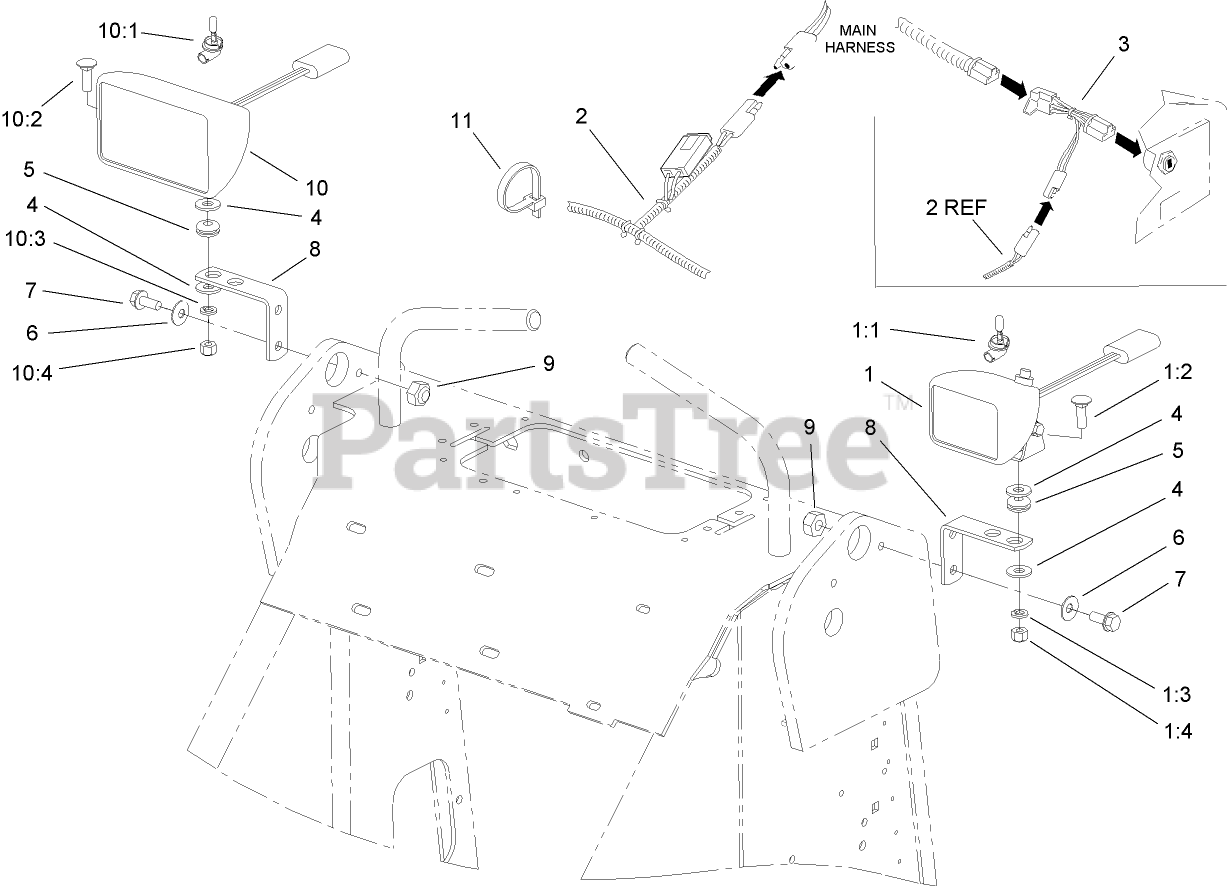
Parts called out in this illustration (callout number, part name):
1	LAMP W/SWITCH
1:1	LAMP-12 VOLT
1:2	SCREW-CARR
1:3	WASHER-LOCK
1:4	NUT-HEX
2	HARNESS-ELECTRICAL
3	HARNESS-ELECTRICAL
4	WASHER-FLAT
5	GROMMET-RUBBER
6	WASHER-BELLEVILLE
7	SCREW-HWHTF
8	Bracket-Light
9	NUT-LOCK, NI
10	LAMP ASM
10:1	LAMP-12 VOLT
10:2	SCREW-CARR
10:3	WASHER-LOCK
10:4	NUT-HEX
11	TIE-CABLE
